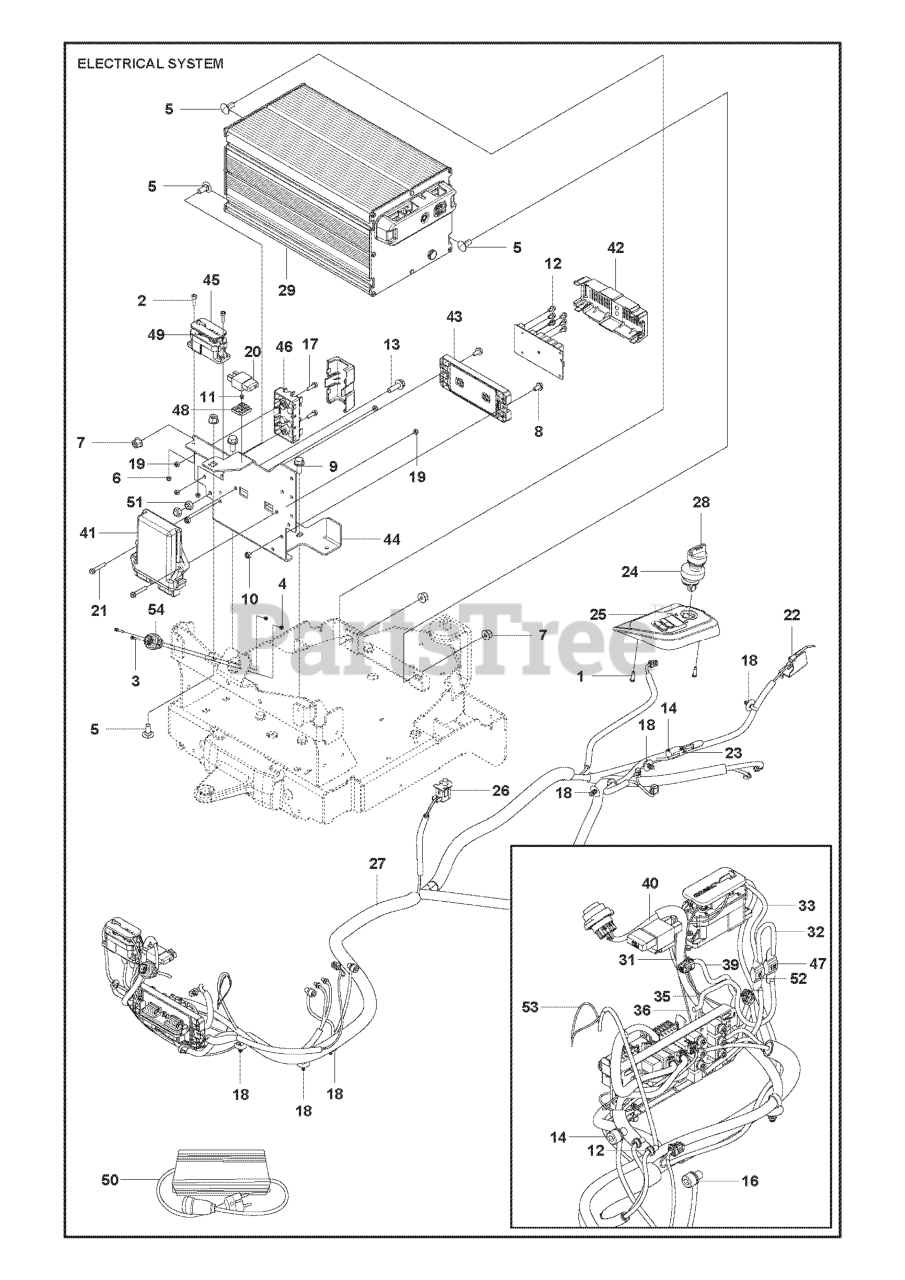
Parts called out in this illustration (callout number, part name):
1	SCREW ITXPANT T50X16 ZN/FE (A
2	SCREW ITXSCM M4X15 T27 12.9 T
4	NUT M6M M3
6	NUT M4
7	NUT FLANGE
8	SCREW EHHFM
10	LOCKNUT M6
12	SCREW ITXSCFM M5X8 T27 10.9 Z
16	WASHER BRB 8.4X17
19	LOCKNUT M5
23	MICRO SWITCH
26	REVERSE SWITCH
51	LOCKNUT M8
